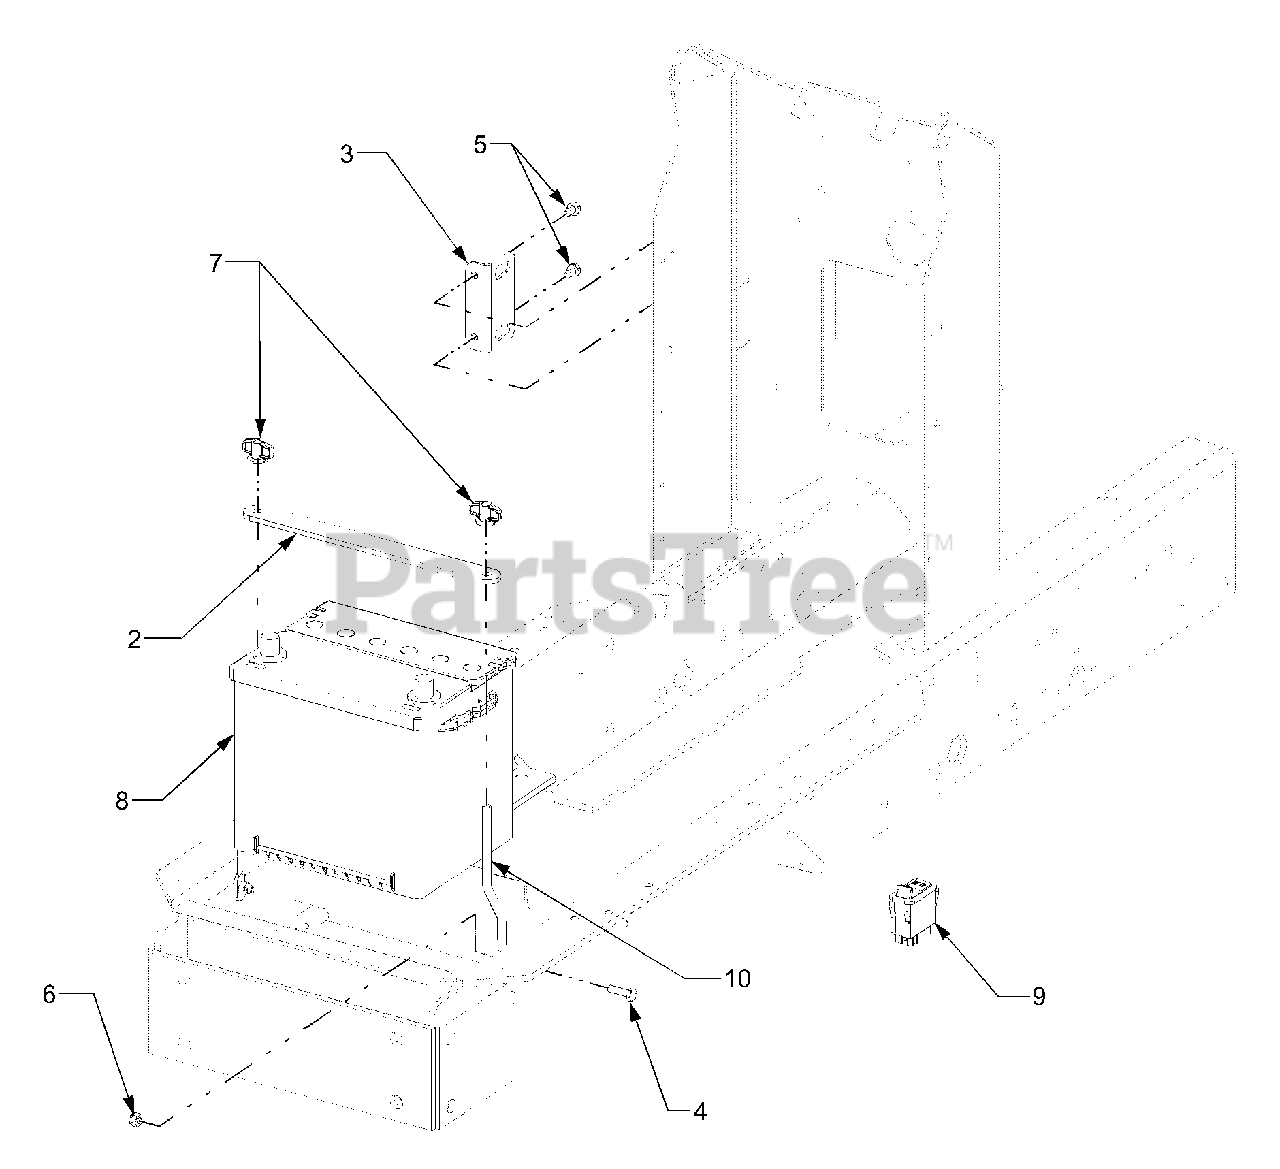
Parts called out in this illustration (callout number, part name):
2	Strap, Battery Holddown
5	Screw, Hex Wash Hd. Tapp 1/4-20 x .5
6	Nut, Hex Nylon Insert Lock, 1/4-20
7	Nut, Wing w/Bell Washer, 5/16-18
8	Battery, 500 cca Dry
9	Switch, PTO Reverse Override
10	Rod, Battery Holddown
